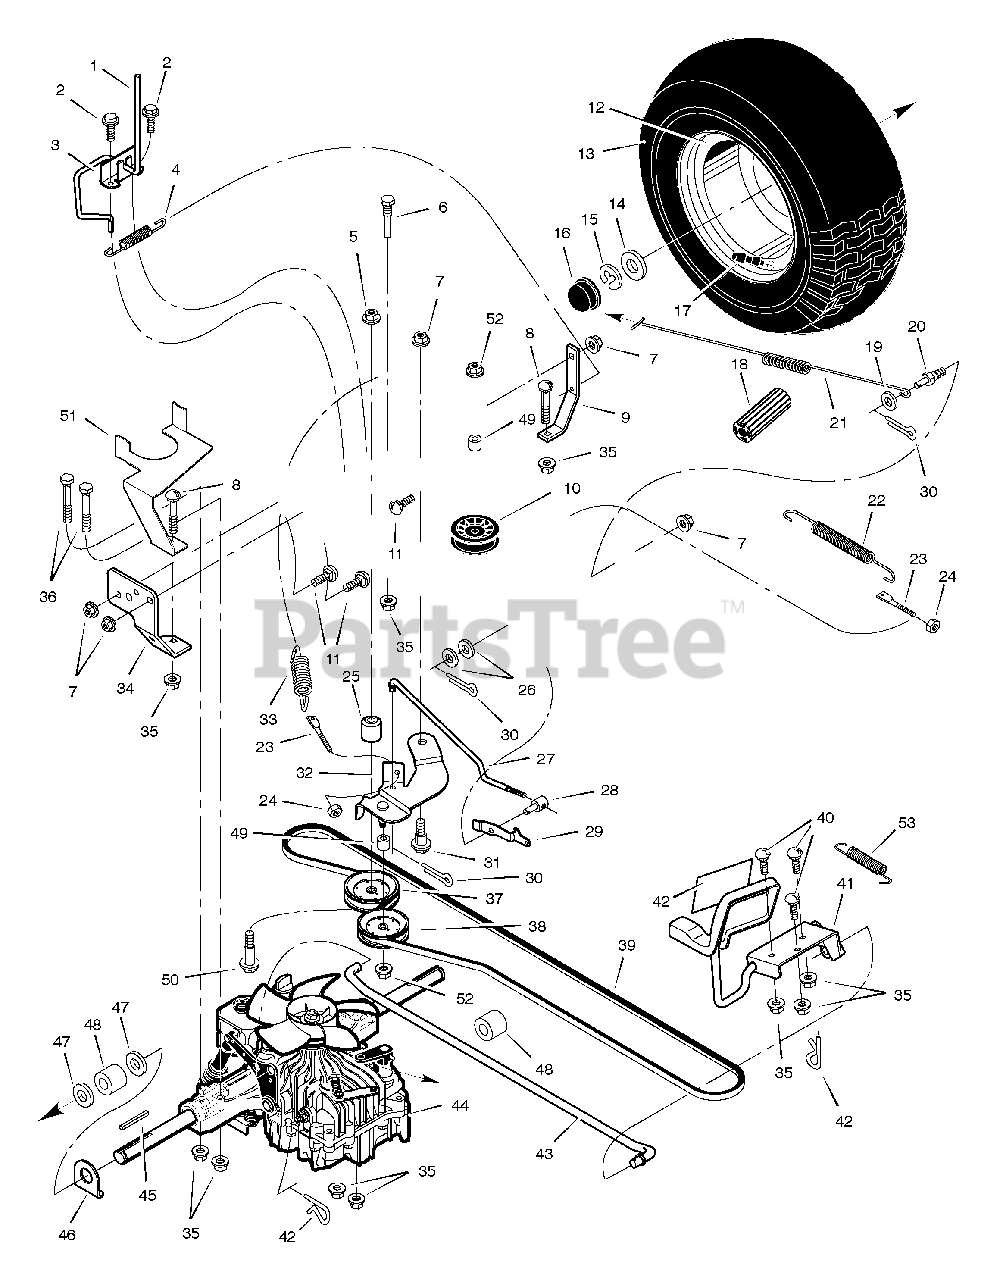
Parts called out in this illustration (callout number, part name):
1	Rod, Cable
3	Bracket, Dump Valve
4	Spring, Extension
5	Locknut
6	Guide, Belt
7	Locknut
8	Bolt, Carriage
9	Bracket, Torque
10	Pulley, Idler
11	Bolt, Carriage
12	Assembly, Wheel and Tire
13	Tire Only *
16	Cap, Hub
17	Stem, Valve
18	Pedal
19	Washer
20	Stud, Threaded
21	Spring, Extension
22	Spring - Extension
23	Stud, Spring Mount
24	Locknut, Flange
25	Spacer
27	Rod, Clutch
28	Nut, Adjusting
29	Latch, Parking Brake
30	Pin, Cotter
31	Bolt, Shoulder
32	Assembly, Idler Arm
33	Spring, Extension
34	Bracket, Torque
35	Nut, Flange
36	Bolt
37	Pulley, Backside Idler
38	Pulley, "V" Idler
39	Belt, Drive
40	Bolt, Carriage
41	Assembly, Pedal
42	Pin, Hair
43	Rod, Hydro Control
44	Transaxle, Hydro Tuff-Torq **
45	Key, Square
46	Washer, Thrust
47	WASHER, 1-1.3 16G FLT
51	Guide, Belt
52	Locknut
53	Spring
54	Pad, Pedal (Forward)
